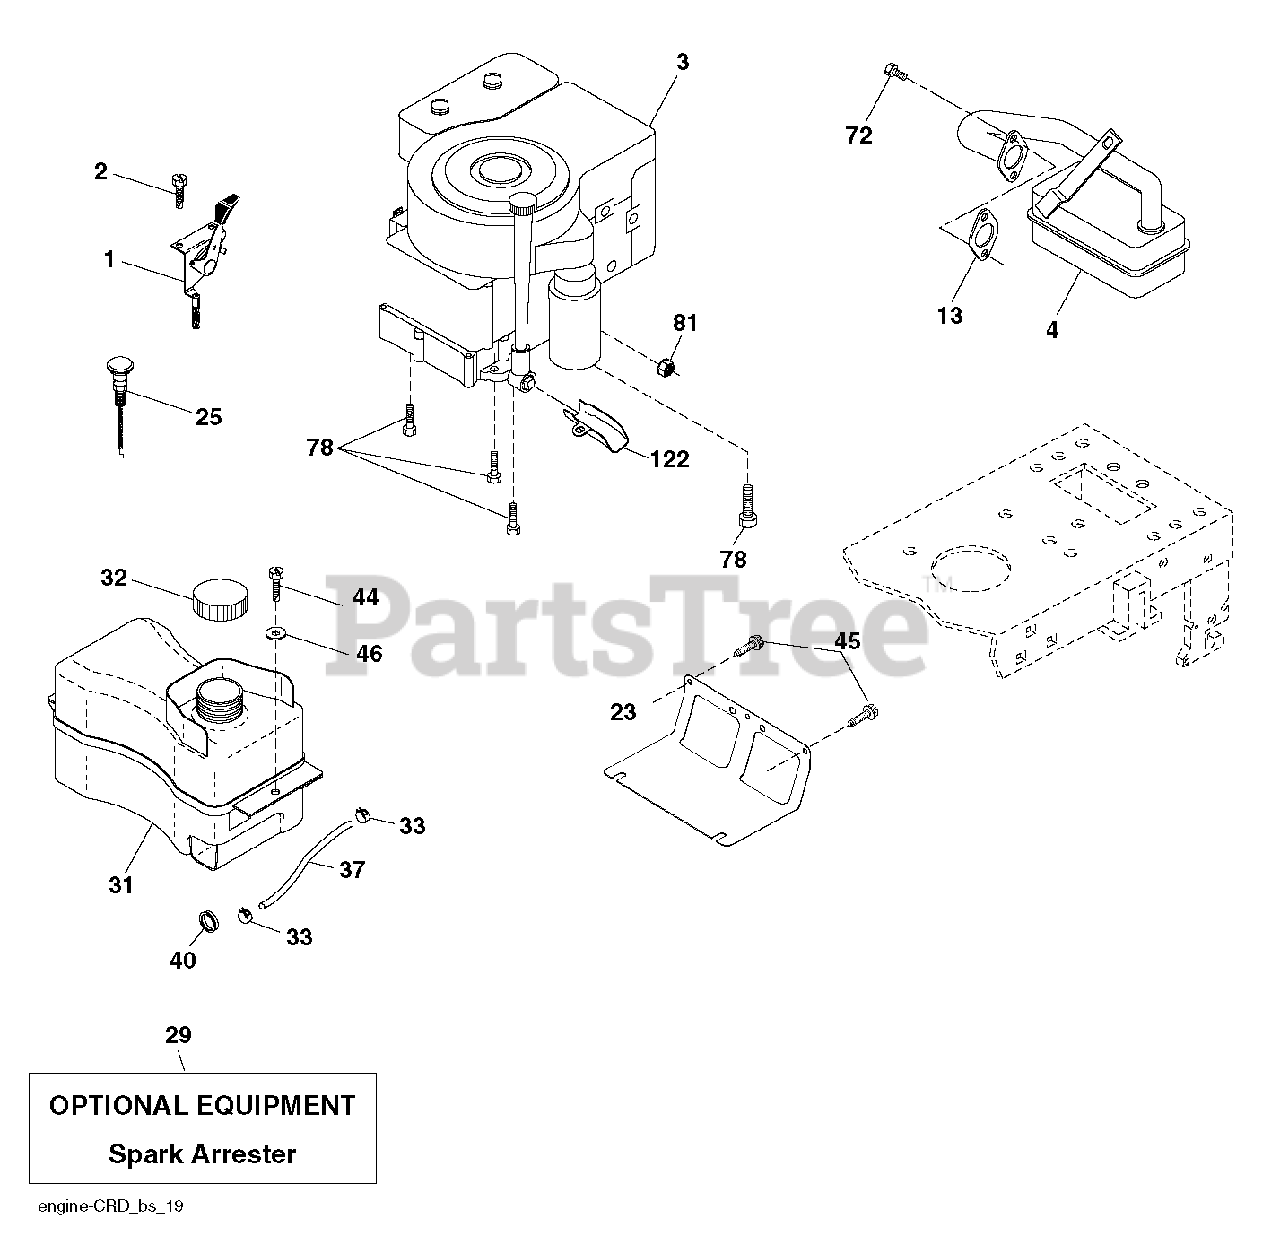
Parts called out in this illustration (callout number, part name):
1	CONTROL.THROTTLE/CHOKE.BLACK
2	SCREW
4	MUFFLER.B&S.MODEL.21.11HP.OHV
23	SHIELD.BROWNING.DBR.GUARD
25	KNOB.ERGO.EXTENDED.RED (1 2)
29	KIT.SPARK ARRESTOR(392390 B&S)
32	CAP ASM.FUEL.2.25"FR.
33	HOSE CLAMP
37	LINE.FUEL.20
40	GROMMET T
44	SCREW HEXWSHR 1/4-20X3/4
45	SCREW, 3/8-16X3/4
72	SCREW.SOCKET HD.5/16-1
78	SCREW.3/8-16
81	NUT
122	EXTENSION DRAIN OIL
